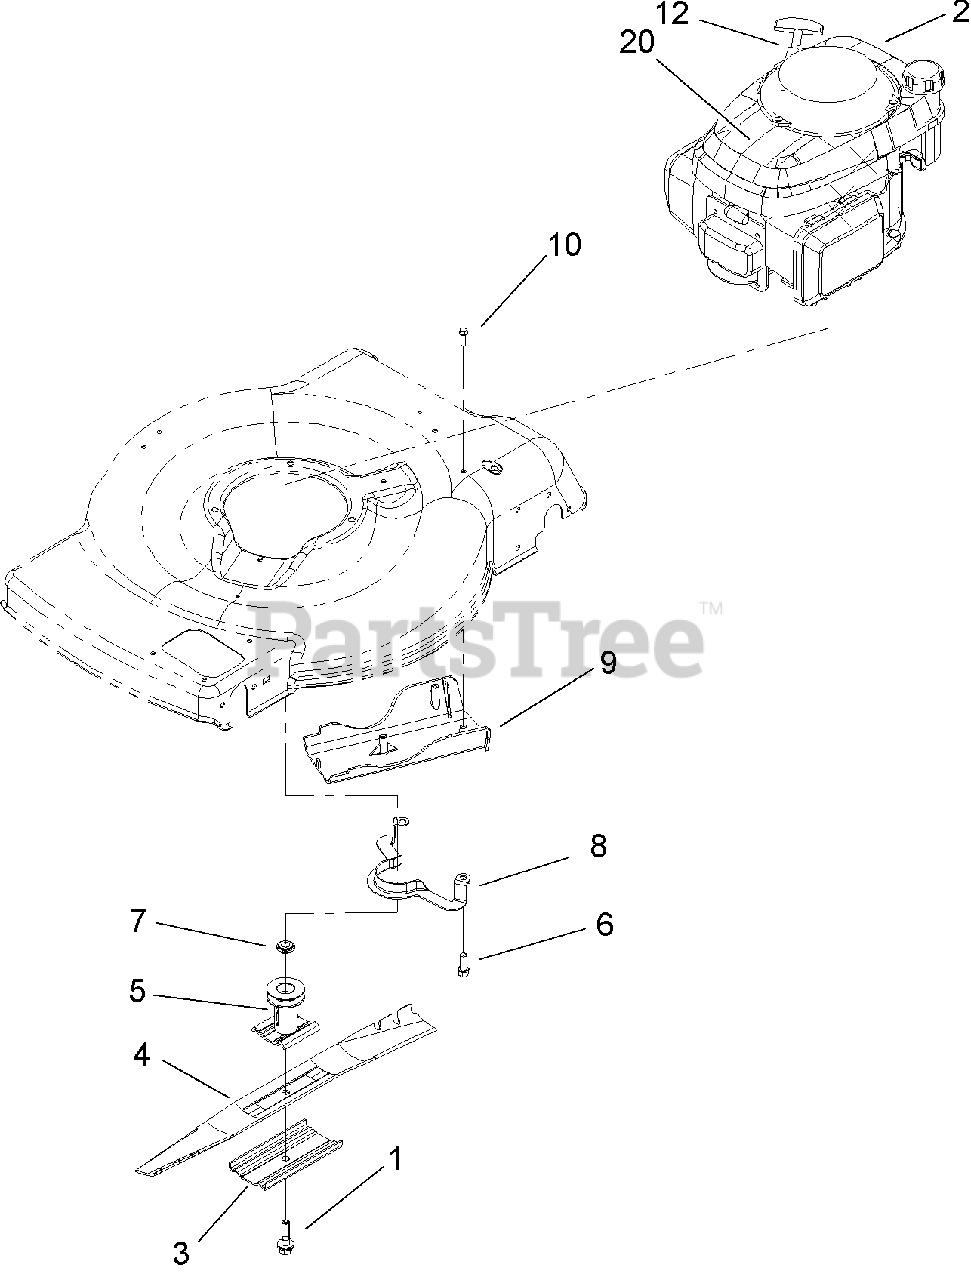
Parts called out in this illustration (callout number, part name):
1	BOLT-BLADE
3	Support-Blade
4	BLADE-22 INCH
5	BLADE DRIVER ASM
6	SCREW-TAPTITE
7	Spacer-Driver
9	Cover-Belt, Rear
10	SCREW-HWH
12	STOP-ROPE
20	DECAL-RECOIL
